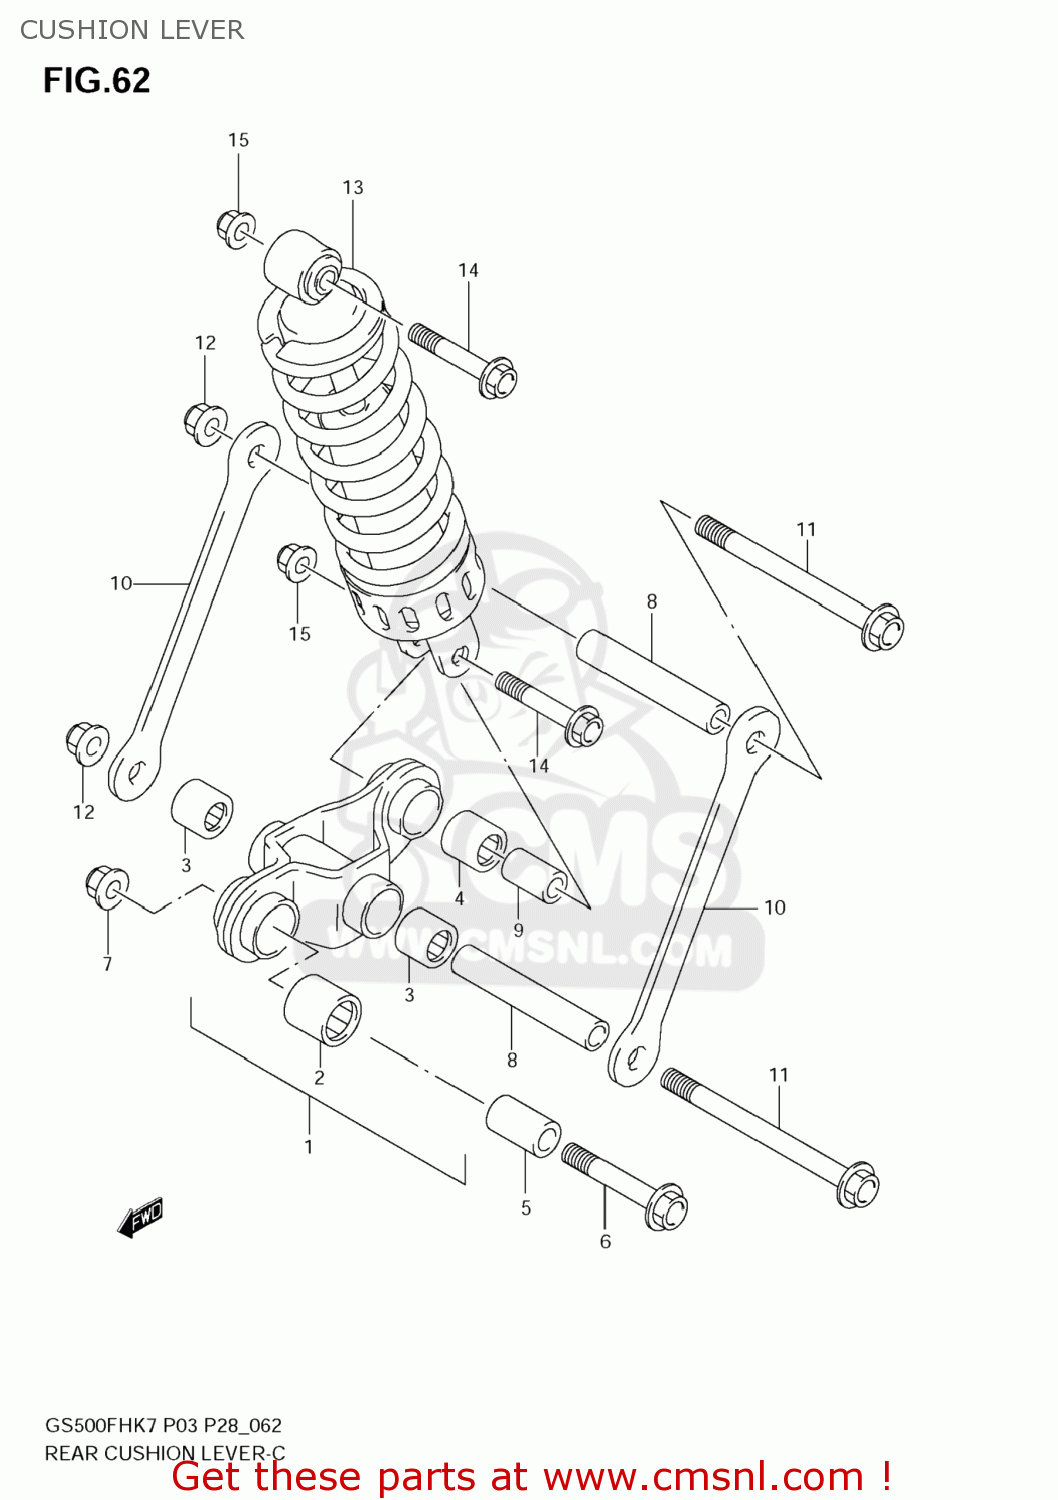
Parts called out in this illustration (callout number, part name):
1	LEVER SET,REAR
2	BEARING(20X27X26)
3	BEARING(17X24X25)
4	BEARING(17X24X26)
5	SPACER, FRONT (12X20X30)
6	BOLT(12X57)
7	NUT
8	SPACER(12X17X89)
9	SPACER, REAR (10X17X30)
10	ROD, REAR CUSHION
11	12
12	NUT
13	ABSORBER ASSY,RR SHOCK
14	BOLT(10X52)
15	NUT
